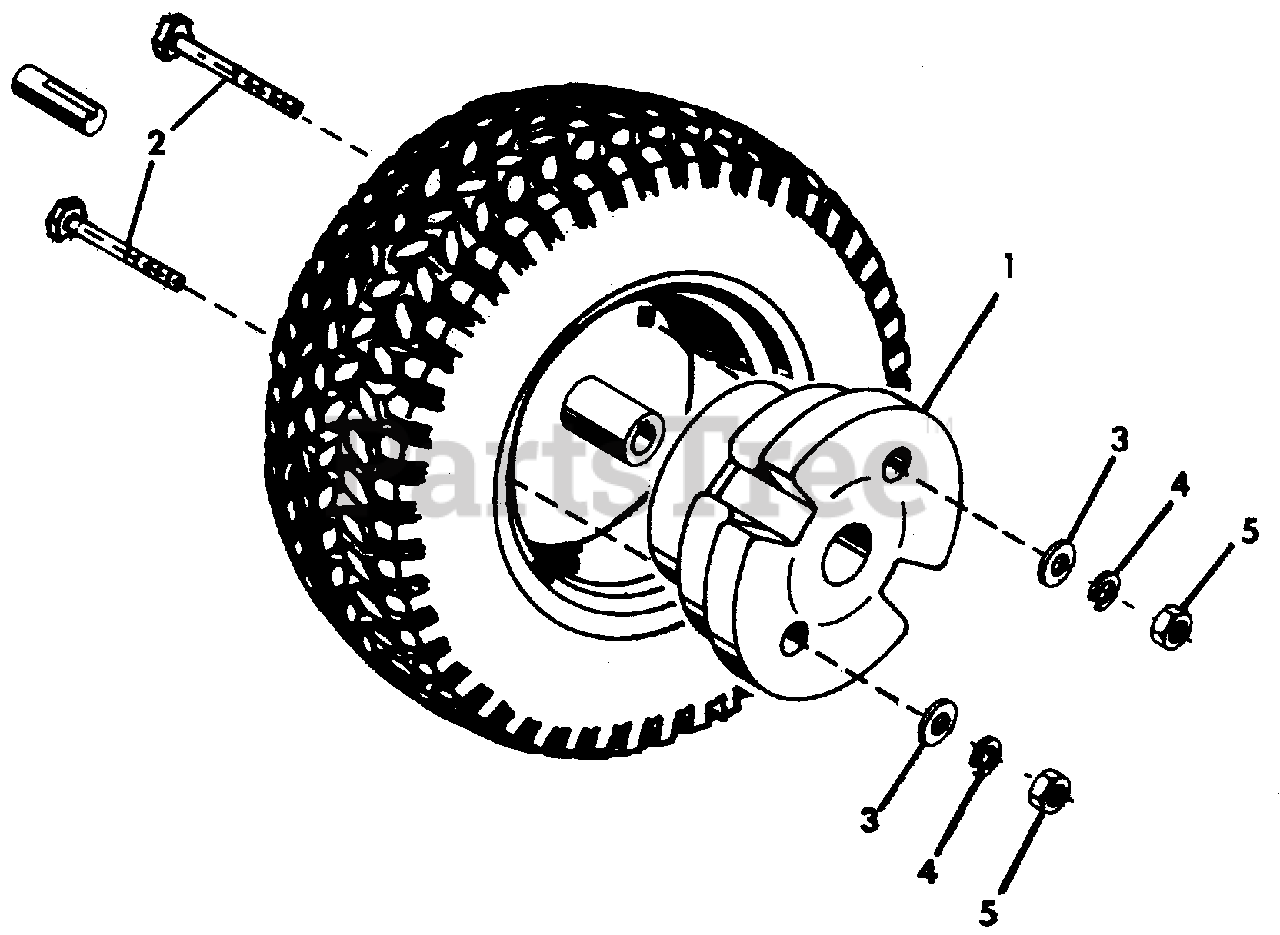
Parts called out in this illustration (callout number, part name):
1	WEIGHT, WHEEL
2	BOLT, HEX 3/8-16 X 5.0
3	WASHER, FLAT .405 X .812 X .065
4	WASHER, LOCK 3/8
5	NUT, 3/8-16
